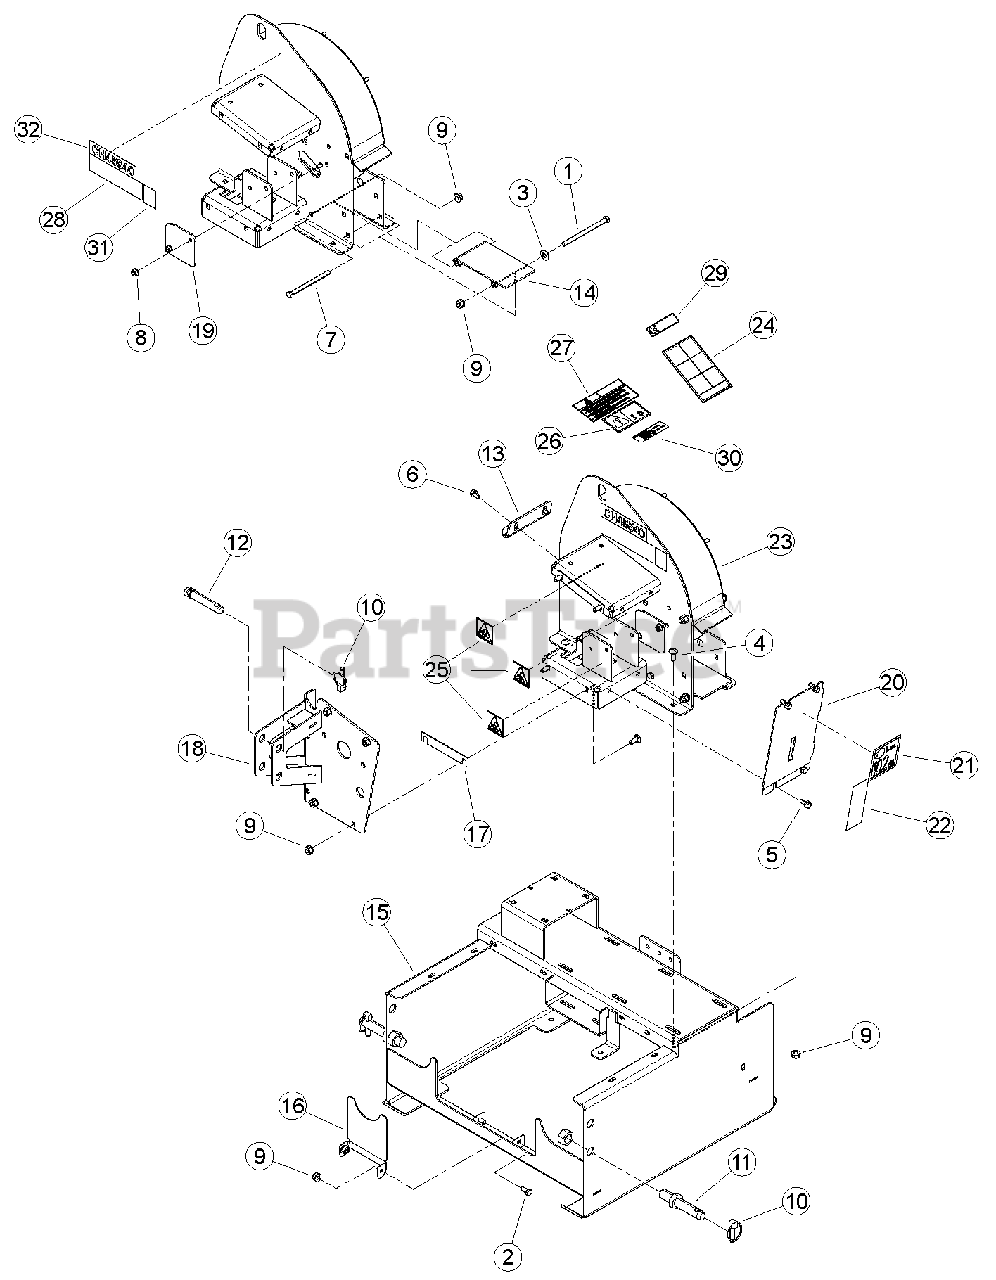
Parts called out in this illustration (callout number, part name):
1	BOLT, 3/8 X 5-1/2 HEX GR5 ZP
2	BOLT, 3/8 X 3/4" GR5 HEX CAPSCREW ZP
3	WASHER, 3/8" FLAT ZP
4	BOLT, 3/8 X 1" CRG GR5 NC ZP
5	BOLT, 5/16 X 3/4 FLANGE NC
6	BOLT, 5/16 X 5/8 FLANGE NC
7	BOLT, 3/8 X 5" GR5 HEX CPS ZP
8	NUT, 5/16-18 NYLOCK-FLANGE
9	NUT, 3/8-16 NYLOCK FLANGE
10	PIN, 7/16 X 1-3/4 LYNCH
11	PIN, LIFT ARM 7/8 X 5" LG
12	PIN, TOP LINK 3/4 X 4-1/2" LG
13	GUIDE, BELT
14	WELDMENT, CHIP DEFLECTOR
15	WELDMENT, CHIPPER 3 PT.
16	PLATE, PTO HOLDER
17	SHIM, 4-1/2 INCH CHIPPER
18	WELDMENT, BEARING SUPPORT
19	PLATE, BOLT ACCESS COVER
20	ASSEMBLY, PTO SIDE PANEL
21	DECAL, 102 DB
22	DECAL, CHIPPER ENGAGEMENT
23	ASSEMBLY, CHIPPER HOUSING
24	DECAL, OPERATING INSTRUCTIONS ISO
25	DECAL, SHIELD DANGER ISO
26	DECAL, MAINTENANCE ISO
27	DECAL, MUTILINGUAL MANUAL
28	DECAL, ECHO BEARCAT 6.82 X 1.90
29	DECAL, 77454S INFORMATION
30	DECAL, ATLANTIC BRIDGE LTD INFO
31	DECAL, ECHO BEARCAT QR CODE
32	DECAL, MODEL CH45540
